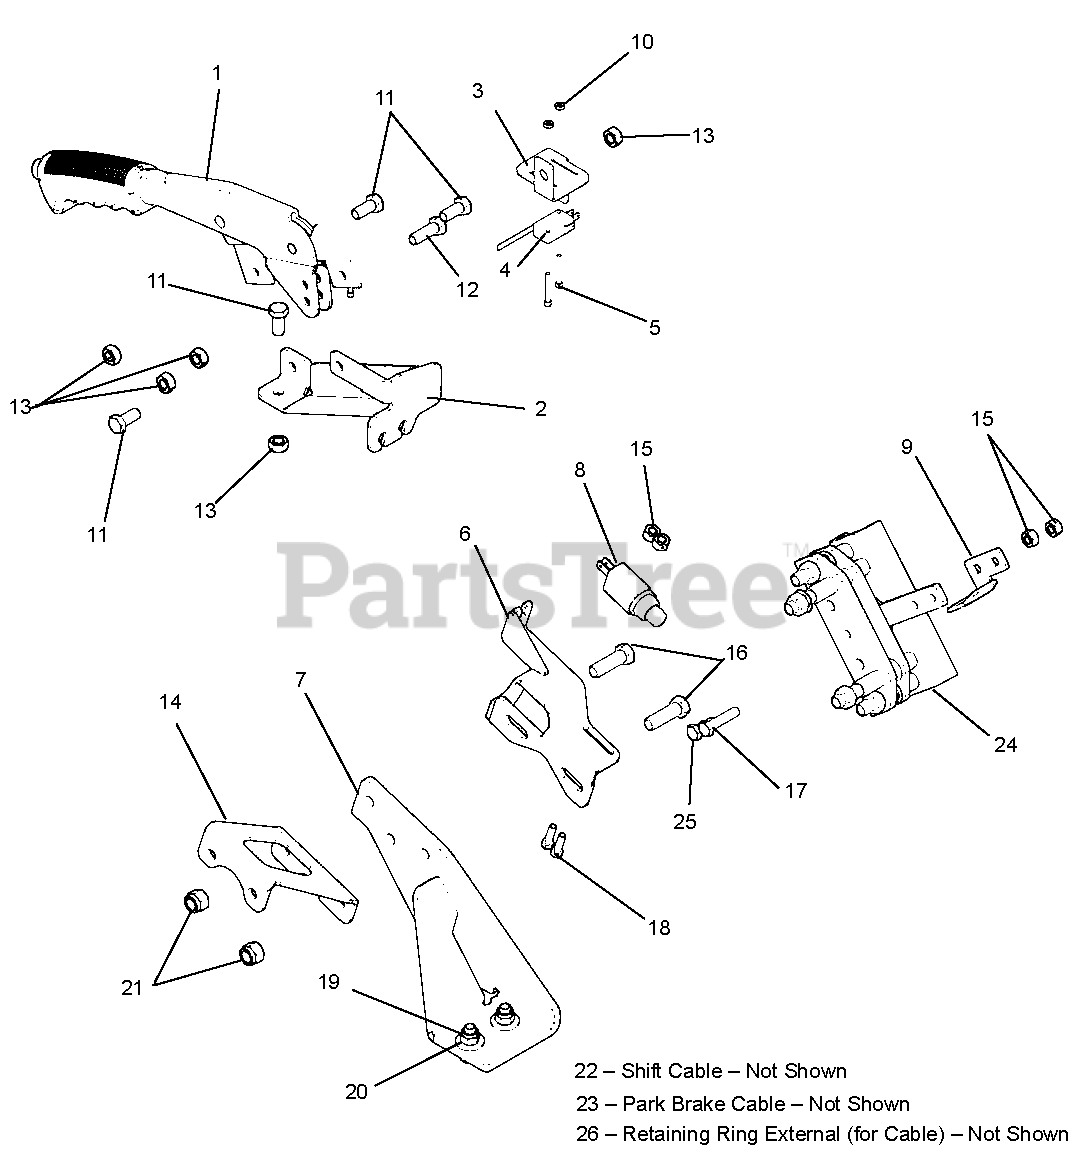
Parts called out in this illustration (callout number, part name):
1	PARK BRAKE LEVER
2	BRACKET, E-BRAKE MNT
3	BRACKET, PARK SWITCH
4	PARK BRAKE MICRO-SWITCH
5	HSHCS #4-40 X 1
6	CABLE MNT, PARK BRAKE
7	BRACKET, CALIPER MNT
8	SWITCH, (N.O.) RUBBER SEALED
9	MOUNT, SWITCH, PARK BRAKE
10	NUT, HEX 4-40 GR5 YWZC
11	BOLT, HEX .31-18 X .75 GR5 YWZC
12	BOLT, HEX .31-18 X 1.00 GR5 YWZC
13	NUT, HEX CENTER LOCK .31-18
14	BRACE, CALIPER MNT, P-BRAKE
15	NUT, LOCK CENTER H10-24 YWZC
16	BOLT, HEX .38-16 X 1.25 GR5 YWZC
17	BOLT, HEX .25-20 X 1.25 GR5 YWZC
18	BOLT, HEX 10-24 X .75 PL GR2
19	NUT, HEX NYLOCK .312-18
20	WASHER, FLAT STEEL .38 X .875 X .083 YWZC
21	NUT, HEX NYLOCK .38-16
24	BRAKE CALIPER
25	BOLT, HEX .25-20 X .75 GR5 YWZC
26	RETAINING RING EXTERNAL
